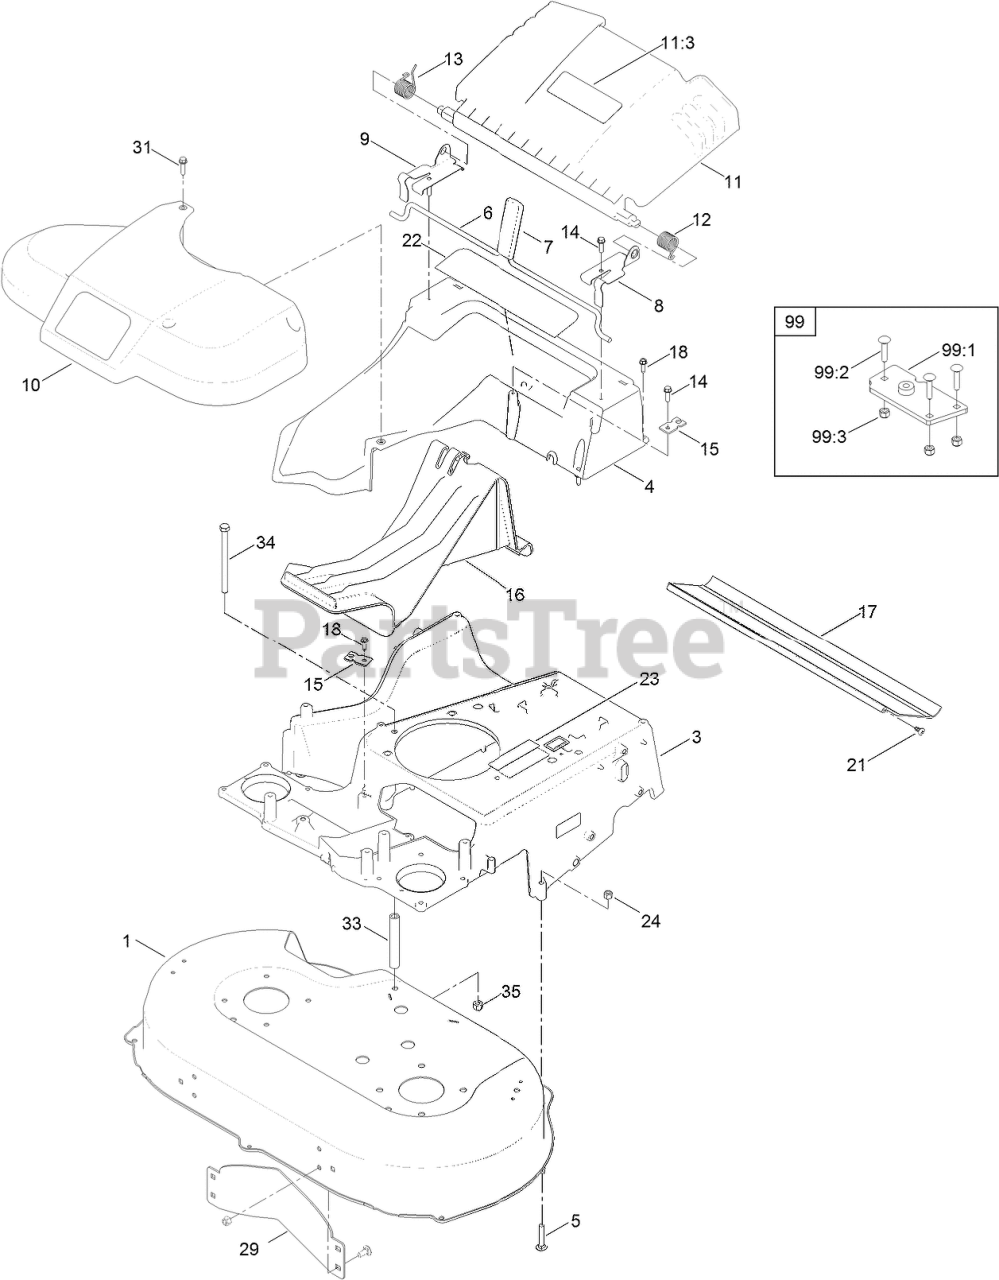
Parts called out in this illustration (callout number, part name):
1	HOUSING ASM
3	FRAME
5	BOLT-CAR
6	ROD-RELEASE, HANDLE
7	GRIP-LEVER
8	BRACKET-DOOR, LH
9	BRACKET-DOOR, RH
10	BELT COVER ASM
11	REAR DEFLECTOR ASM
11:3	DECAL-WARNING
12	SPRING-TORSION
13	SPRING-TORSION
14	SCREW-HWH
16	PLUG-MULCH
17	SHIELD-TRAILING
18	SCREW-HWHTF
21	SCREW-PTH
22	DECAL-POSITION, HANDLE
23	DECAL-ARRESTER, SPARK
24	NUT-LOCK, NI
29	BAFFLE-CONTROL
31	SCREW-HWHTF
33	SPACER-SHIELD
34	SCREW-HH
35	NUT-LOCK, NI
99	FRAME PLATE KIT
99:1	PLATE-FRAME
99:2	SCREW-CARR
99:3	NUT-LOCK, NI
